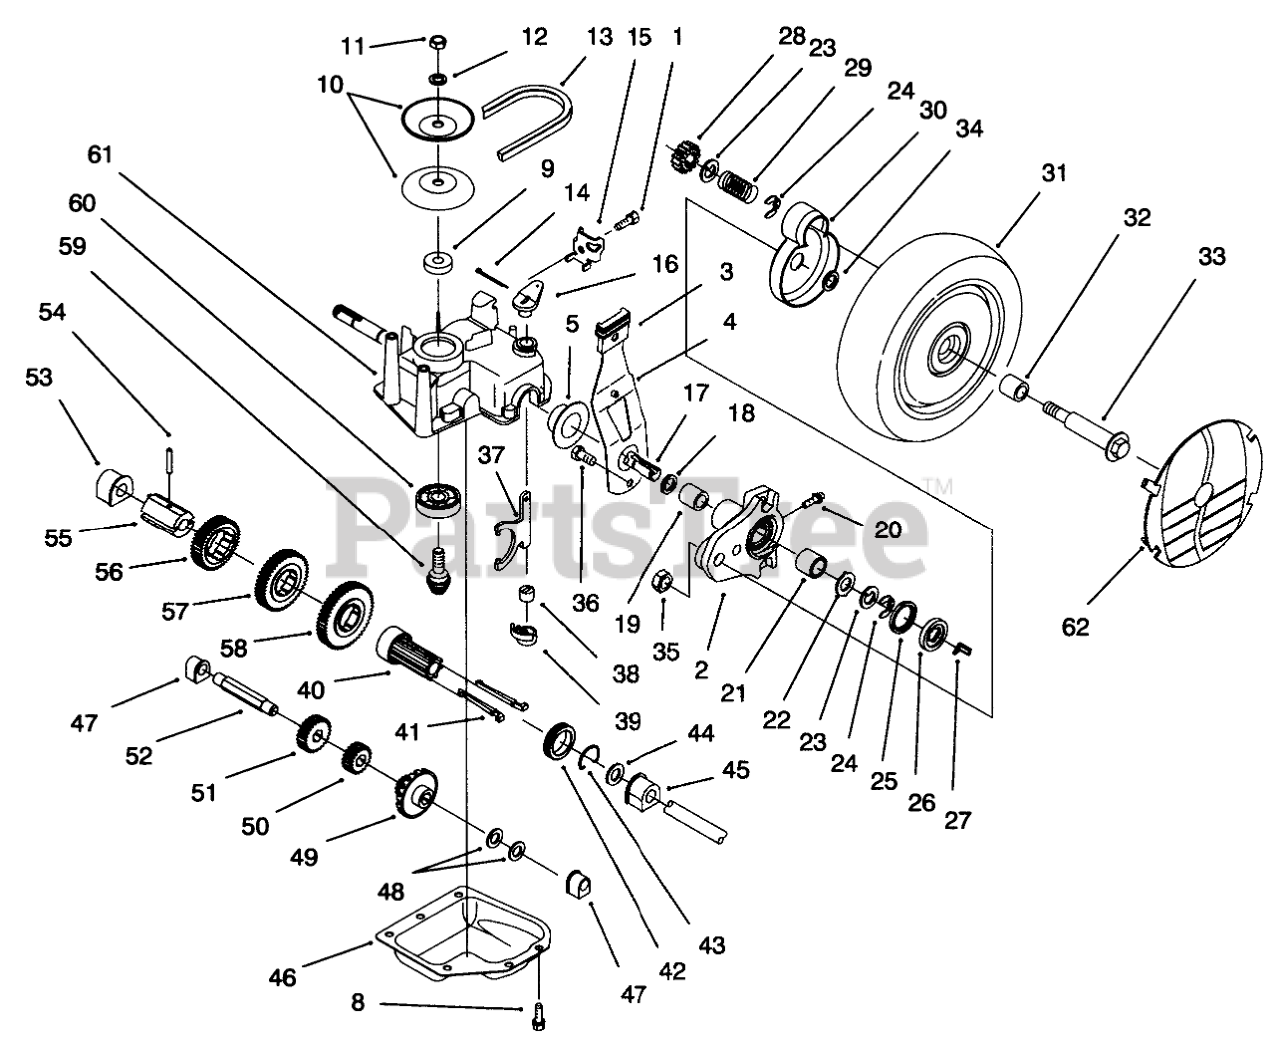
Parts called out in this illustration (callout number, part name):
1	SCREW-HWHTF
2	Pivot Arm Assembly (Incl. Ref. #19-21)
3	KNOB-ARM
4	SPRING ARM ASM
5	CAP-END
8	SCREW-HWHTF
9	SPACER
10	Pulley Half
11	NUT-HEX
12	WASHER-FLAT
13	V-BELT E
14	PIN-COTTER
15	CLAMP-CABLE
16	LEVER-SHIFT
17	SHAFT-OUTPUT
18	O-RING
19	BUSHING
20	FITTING-GREASE
21	BEARING-ROLLER
22	WASHER-ARM, PIVOT
23	WASHER-THRUST, KEYED
24	RING-CLIP, LOCKING
25	RING-FRICTION
26	WASHER-CLUTCH
27	KEY-ROCKING, LH
28	GEAR-PINION
29	SPRING-COMPRESSION
30	COVER-WHEEL
31	Wheel Tire & Gear Assy. (Incl. Ref. #32)
32	BUSHING
33	BOLT-WHEEL
34	SPACER-COVER, WHEEL
35	NUT-LOCK
36	SCREW-HWH
37	YOKE-SHIFT
38	BUSHING-YOKE
39	RETAINER-FORK, SHIFT
40	SLEEVE-KEY, SHIFT
41	KEY-SHIFT
42	COLLAR-SHIFT
43	CLIP-SPRING
44	WASHER-PLAIN
45	BUSHING-OUTPUT
46	Cover-Gearcase
47	BUSHING
48	WASHER-THRUST
49	Gear-Bevel
50	PINION-20T
51	PINION-25T
52	SHAFT-INTERMEDIATE
53	BUSHING
54	PIN-SPRING
55	SLEEVE-GEAR
56	GEAR-39T
57	GEAR-44T
58	GEAR-49T
59	Gear-Pinion
60	BEARING-BALL
61	CASE-GEAR, UPPER
62	COVER-WHEEL
